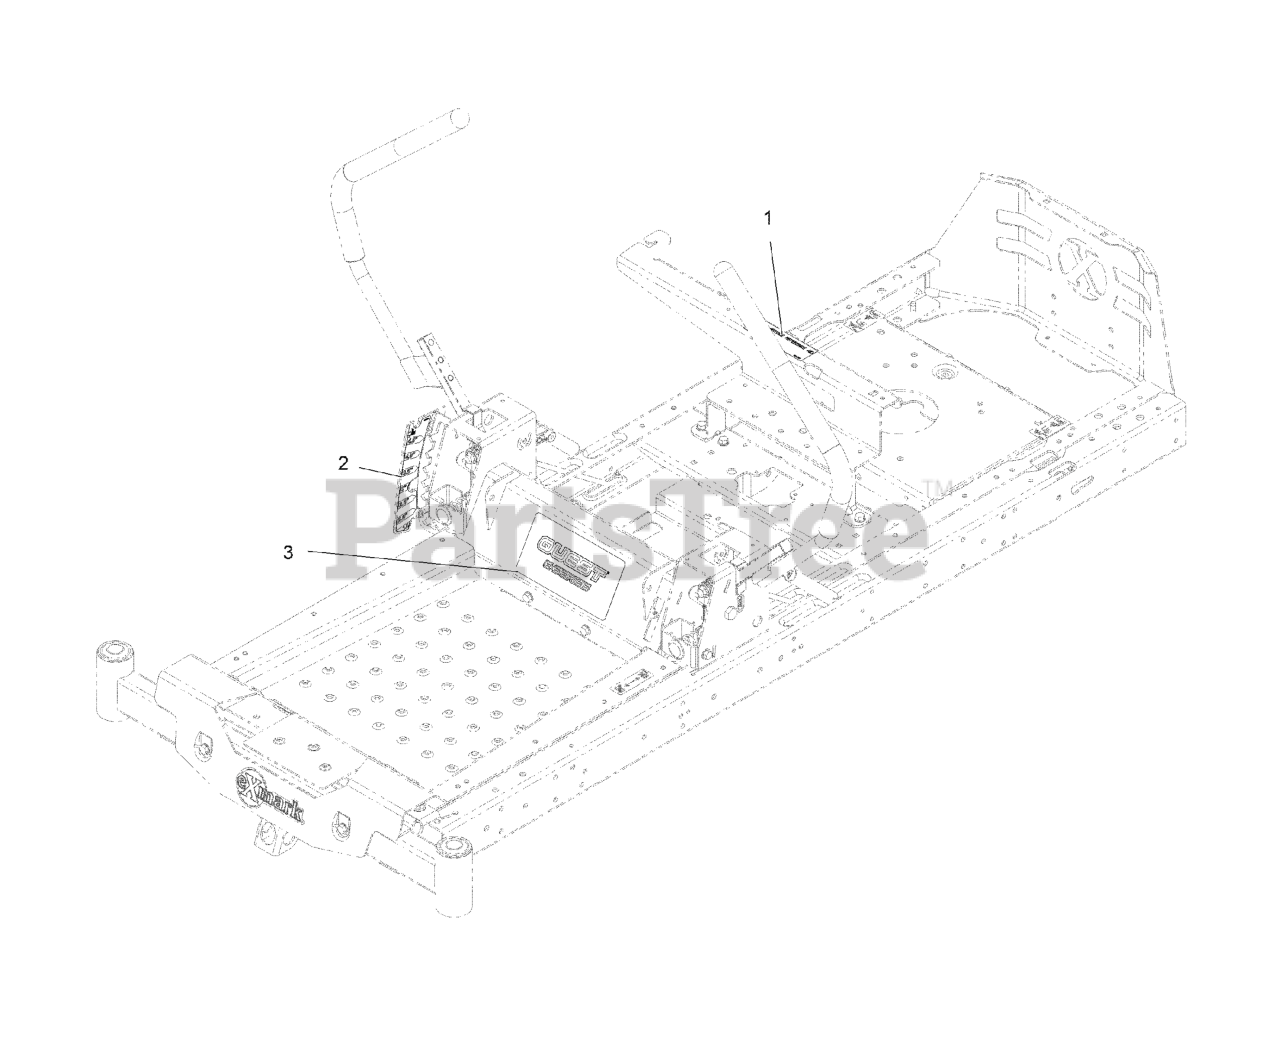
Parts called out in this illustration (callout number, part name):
1	DECAL-SERVICE, CE
2	DECAL-HOC
3	DECAL, QUEST E SERIES
